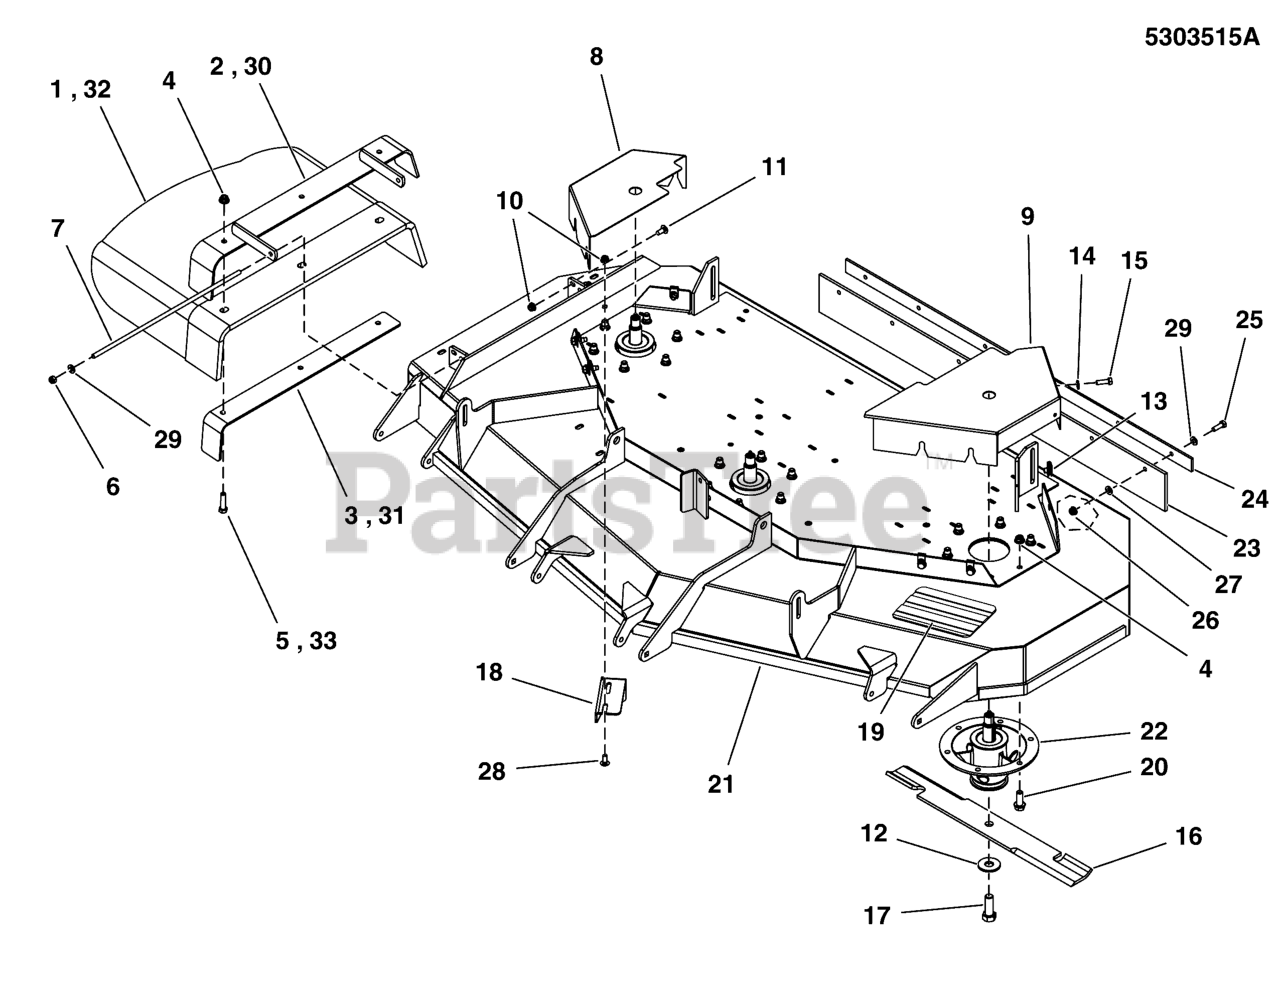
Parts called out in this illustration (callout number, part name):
1	CHUTE, DISCHARGE, BEND RUBBER (SV)
2	WELD, FRAME CHUTE, 61 - BLK
3	SUPPORT, DICHARGE CHUTE, 61/72 - BLK
4	NUT, 3/8-16 HEX NYLOCK FLANGE
5	BOLT, 3/8-16 X 1-1/2" GD5 CZ
6	NUT, 5/16-24 HEX NYLON LOCK
7	ROD, MOUNT, CHUTE 61, CZ
8	GUARD, 61", RH - RED
9	GUARD, 61 - LH - RED
10	NUT, 5/16-18 HEX NYLOCK FLANGE
11	BOLT, 5/16-18 X 3/4 GD5
12	WASHER, BLADE BOLT, 9/16" F436, CZ
13	BODY CLIP, 5/16-18-7GA MATERIAL
14	WASHER, 5/16 F436 FLAT
15	BOLT, 5/16-18 X 3/4 GD5
16	BLADE SET, 61 DECK (3)
17	BOLT, 5/8-11 X 1-3/4 GD8
18	PLATE, DEFLECTOR - BLK
19	SAFETY WALK, 9.75 X 6.00
20	BOLT, 3/8-16 X 1, FLANGE, GD 5, CZ
21	DECK SHELL W/ DECALS, 61, IS2100Z (SV)
21	DECK SHELL W/ DECALS, 61, IS2100Z EXP (SV)
22	SPINDLE ASSM, CAST IRON 8.0-6 BOLT
23	FLAP, STRIPER, 61 DECK
24	PLATE, SUPPORT - BLK
25	BOLT, 5/16-18 X 1 GD5 YZ
26	NUT, 5/16-18 HEX NYLOCK FLANGE
27	5/16 PUSH-ON NUT RETAINER, STL, CZ
28	BOLT, 5/16-18 X 3/4, CARRIAGE
29	WASHER, 5/16" SAE
30	MOUNT
31	SUPPORT, DISCHARGE CHUTE - BLK
32	CHUTE, RUBBER DISCHARGE (5104442)
33	BOLT, 3/8-16 X 1-1/2, CARRIAGE, GD5, CZ
